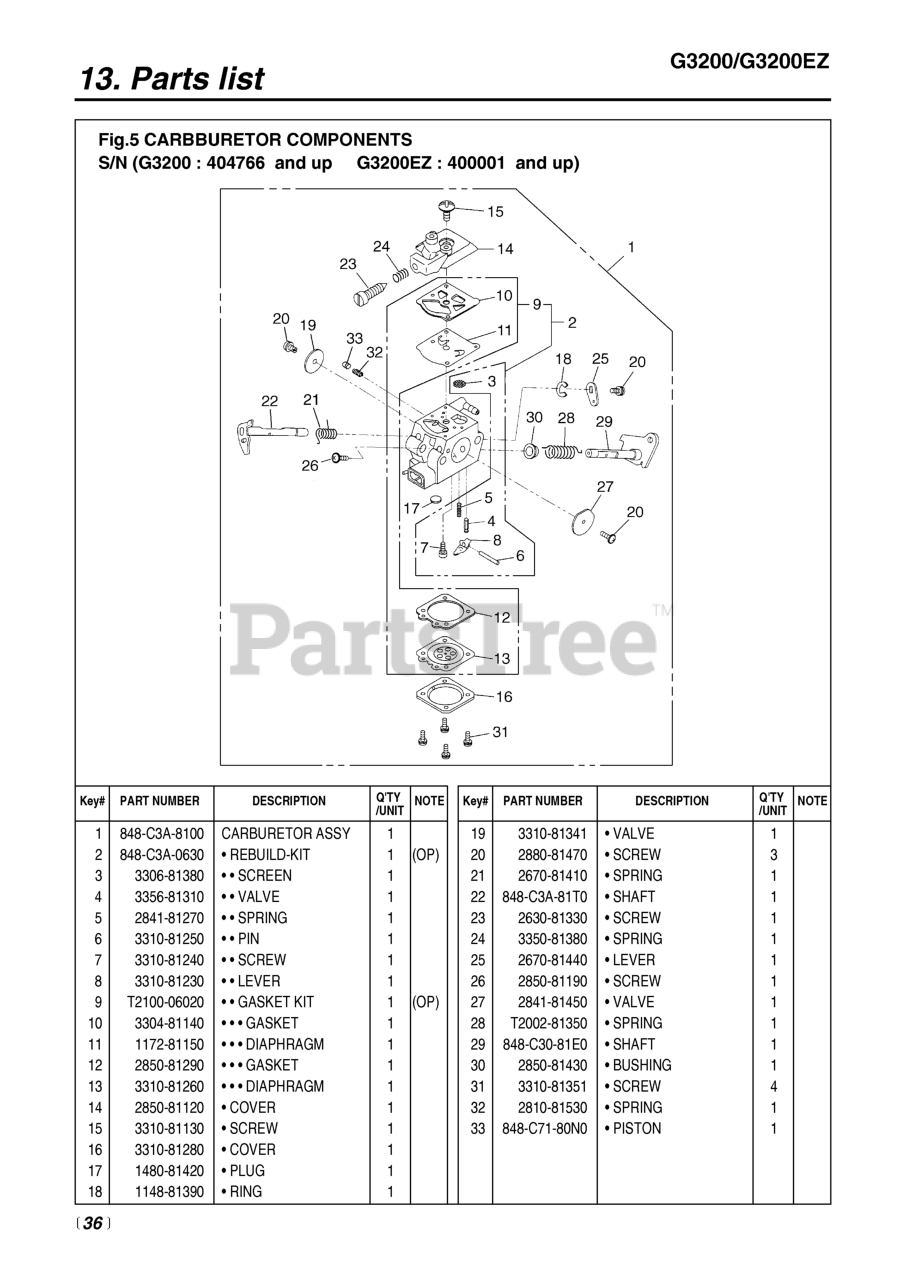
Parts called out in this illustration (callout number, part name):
2	REBUILD KIT
4	VALVE, INLET
5	SPRING (USE 2867-81270)
6	PIN, METERING LEVER
8	LEVER
9	KIT, GASKET (G3800AVS)
10	GASKET, PUMP
11	DIAPHRAGM, PUMP
13	DIAPHRAGM (USE 4810-81260)
14	COVER, PUMP
17	PLUG, WELSH
20	SCREW (RPLS 3310-81360)
21	SPRING, RETURN
24	SPRING, IDLE
25	VALVE, THROTTLE
31	SCREW ASSEMBLY
33	PISTON
